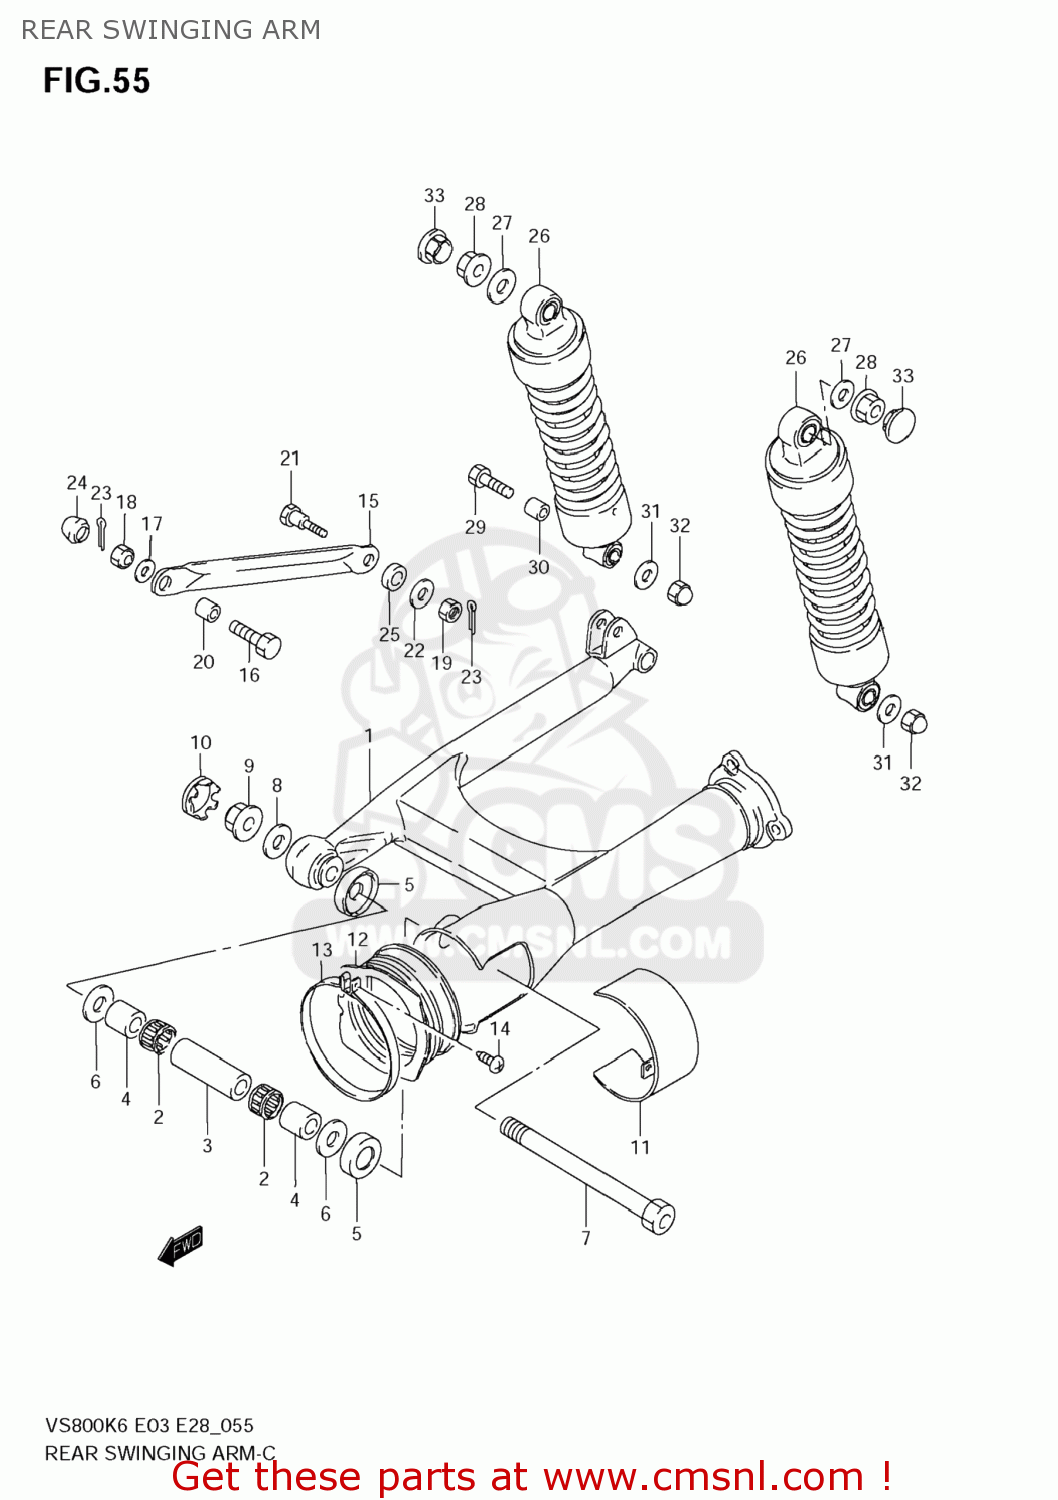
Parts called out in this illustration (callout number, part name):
1	SWINGINGARM,RR
2	BEARING(22X29X20)
3	SPACER,RR SWGARM PIVOT
4	SPACER,RR SWGARM PIVOT
5	SEAL,RR SWGARM PIVOT DUST
6	WASHER
7	SAHFT,RR SWGARM PIVOT
8	WASHER(17X30X3)
9	NUT
10	CAP,RR SWINGING ARM PIVOT,R
11	COVER,RR SWGARM PIVOT,L
12	BOOT,PROPELLER SHAFT
13	CLAMP
14	SCREW
15	TORQUELINK,RR
16	BOLT(10X28)
17	WASHER(10X20X2.3)
18	NUT
19	NUT
20	SPACER(10.2X14X9.6)
21	BOLT(10X41)
22	WASHER(10X20X2.3)
23	PIN
24	CAP
25	CUSHION
26	ABSORBER ASSY,RR SHOCK
27	WASHER(10.5X20X2.3)
28	NUT
29	BOLT(10X39)
30	SPACER(10.2X14X20.7)
31	WASHER(10.5X24X2.3)
32	NUT
33	CAP,FRAME HANDLE GRIP
